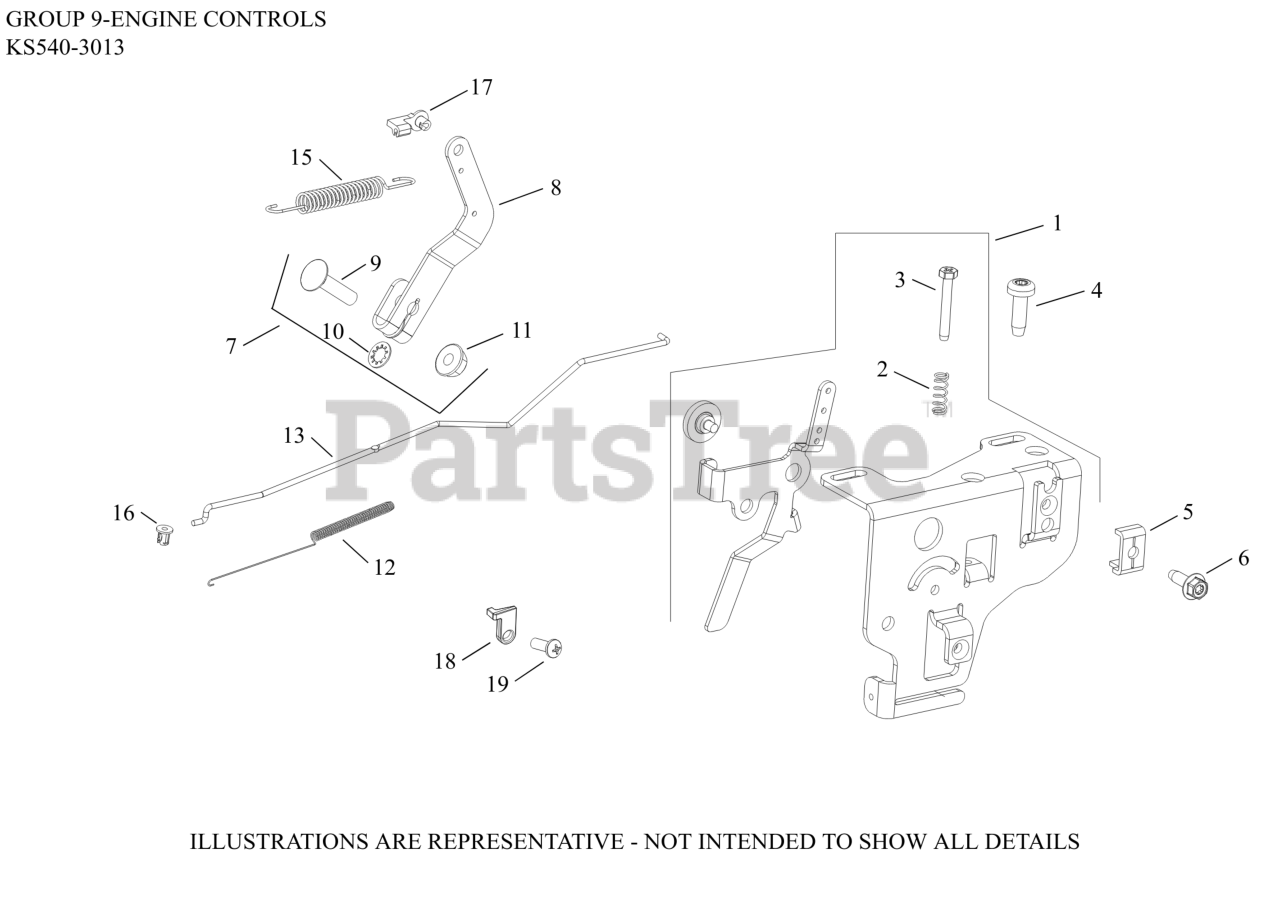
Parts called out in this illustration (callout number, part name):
1	CONTROL ASSY SPEED
2	SPRING, SPEED CONTROL
3	KIT, IDLE ADJ SCREW & SPRING
4	SCREW, THREAD FORMING
5	CLAMP, CABLE-(#2523753S)
6	SCREW, THREAD FORMING
7	LEVER, GOVERNOR ASSY
8	LEVER, GOVERNOR
9	BOLT, RD HD SQ NCK 1/4-20X1"
10	WASHER, INT TOOTH LOCK 1/4"
11	NUT, FLANGE 1/4-20
12	SPRING, LINKAGE
13	LINKAGE, THROTTLE
15	SPRING, GOVERNOR
16	BUSHING, LINKAGE RETAINING
17	BUSHING, THROTTLE LINKAGE
18	CLAMP, CHOKE WIRE HOLD DOWN
19	SCREW, SELF TAPPING
